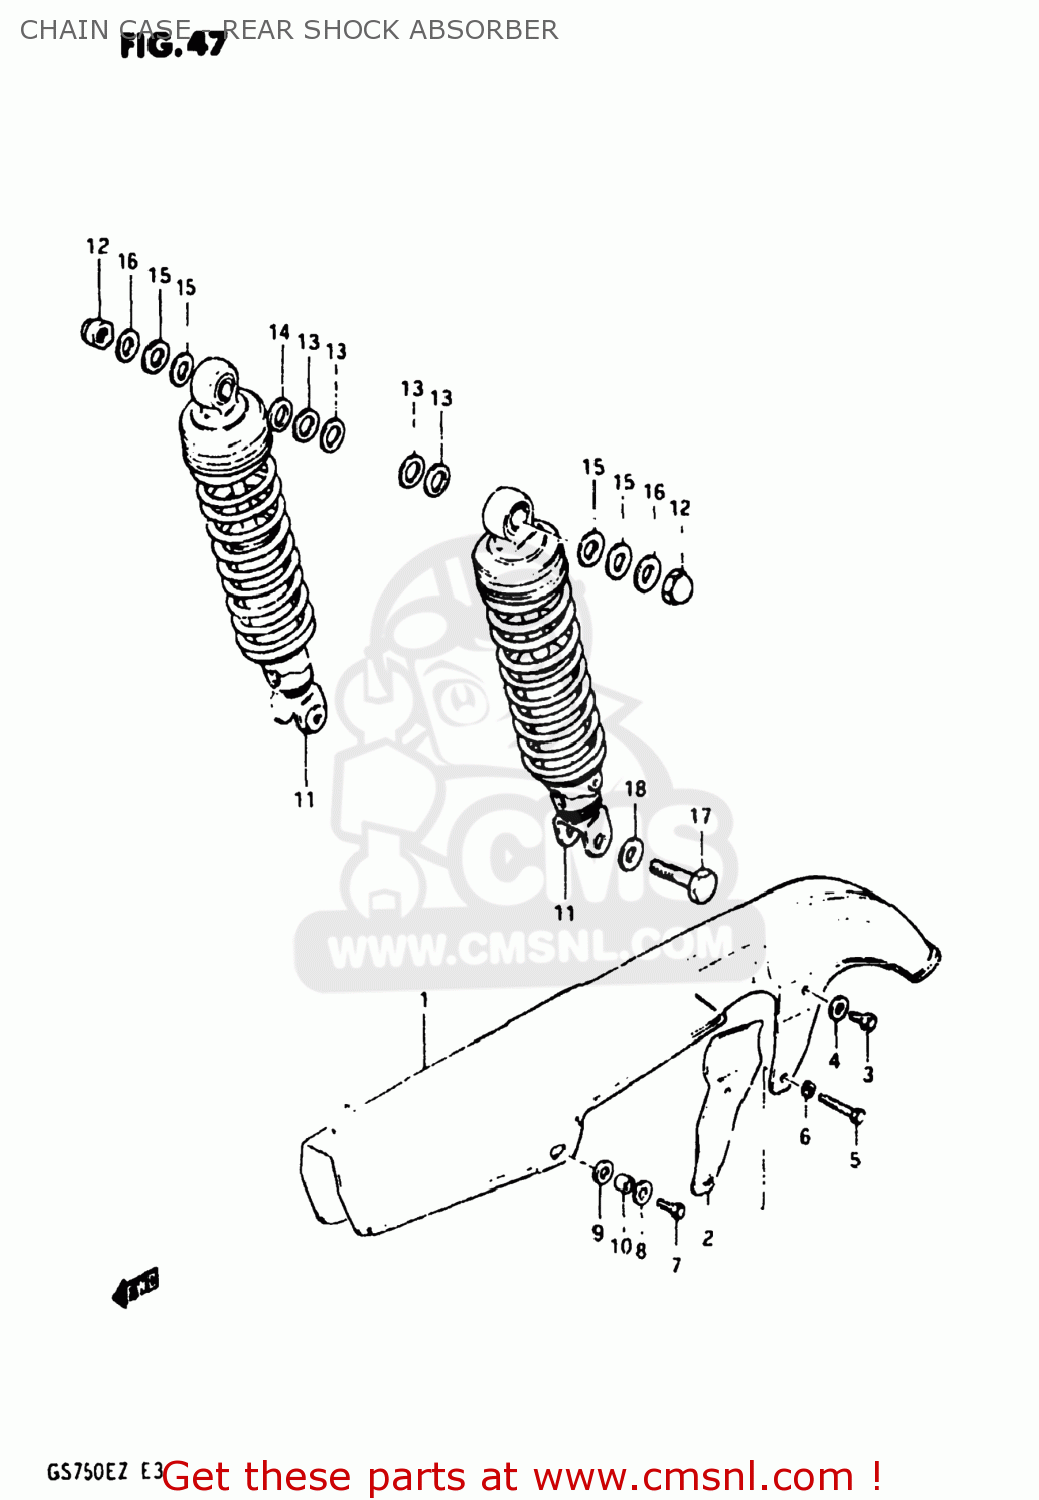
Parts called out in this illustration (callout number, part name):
1	CASE,CHAIN
2	REINFORCEMENT,CHAIN CASE
3	BOLT(6X8)
4	WASHER
5	BOLT
6	LOCK WASHER
7	BOLT
8	WASHER(6.5X18X1)
9	CUSHION
10	SPACER (6.1X8X5.2)
11	ABSORBER ASSEMBLY,REAR SHOCK
12	NUT, LOWER LH
13	WASHER
14	WASHER (12.5X24X3.2)
15	WASHER
16	WASHER(10.5X24X3.2)
17	BOLT(10X36)
18	WASHER
